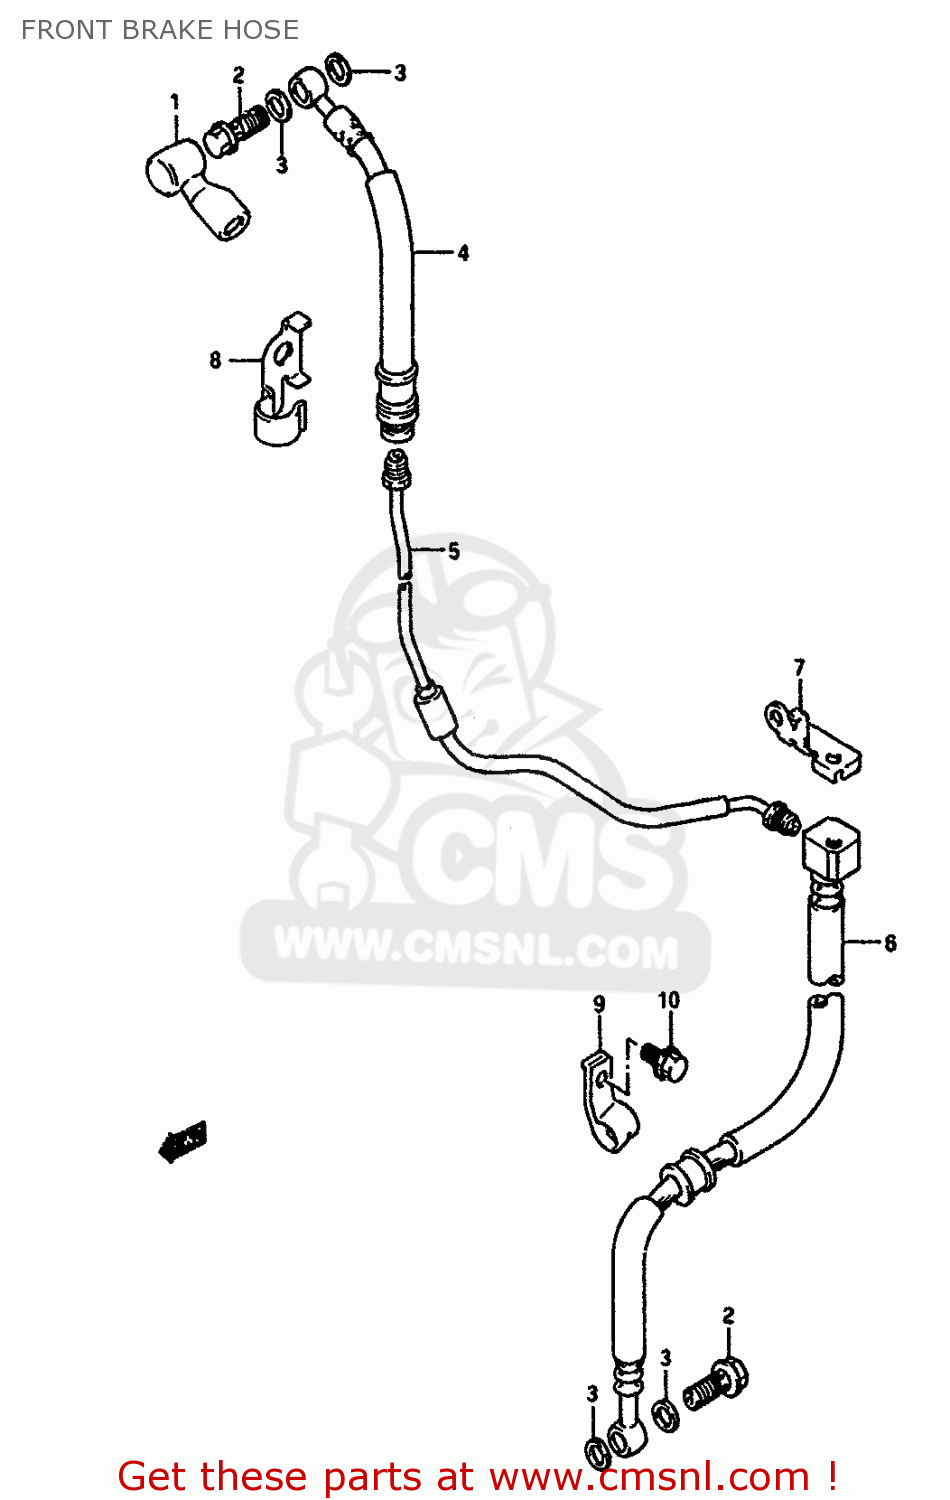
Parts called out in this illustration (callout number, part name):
1	BOOT,MASTER CYLINDER
2	BOLT UNION
3	WASHER(10X15X1.5)
4	HOSE,FR BRAKE NO.1
5	PIPE,FRONT BRAKE
6	HOSE COMP,FRONT BRAKE
7	BRACKET,FRONT BRAKE HOSE
8	CLAMP,FR BRAKE HOSE NO.1
9	CLAMP,FR BRAKE HOSE NO.2
10	BOLT
